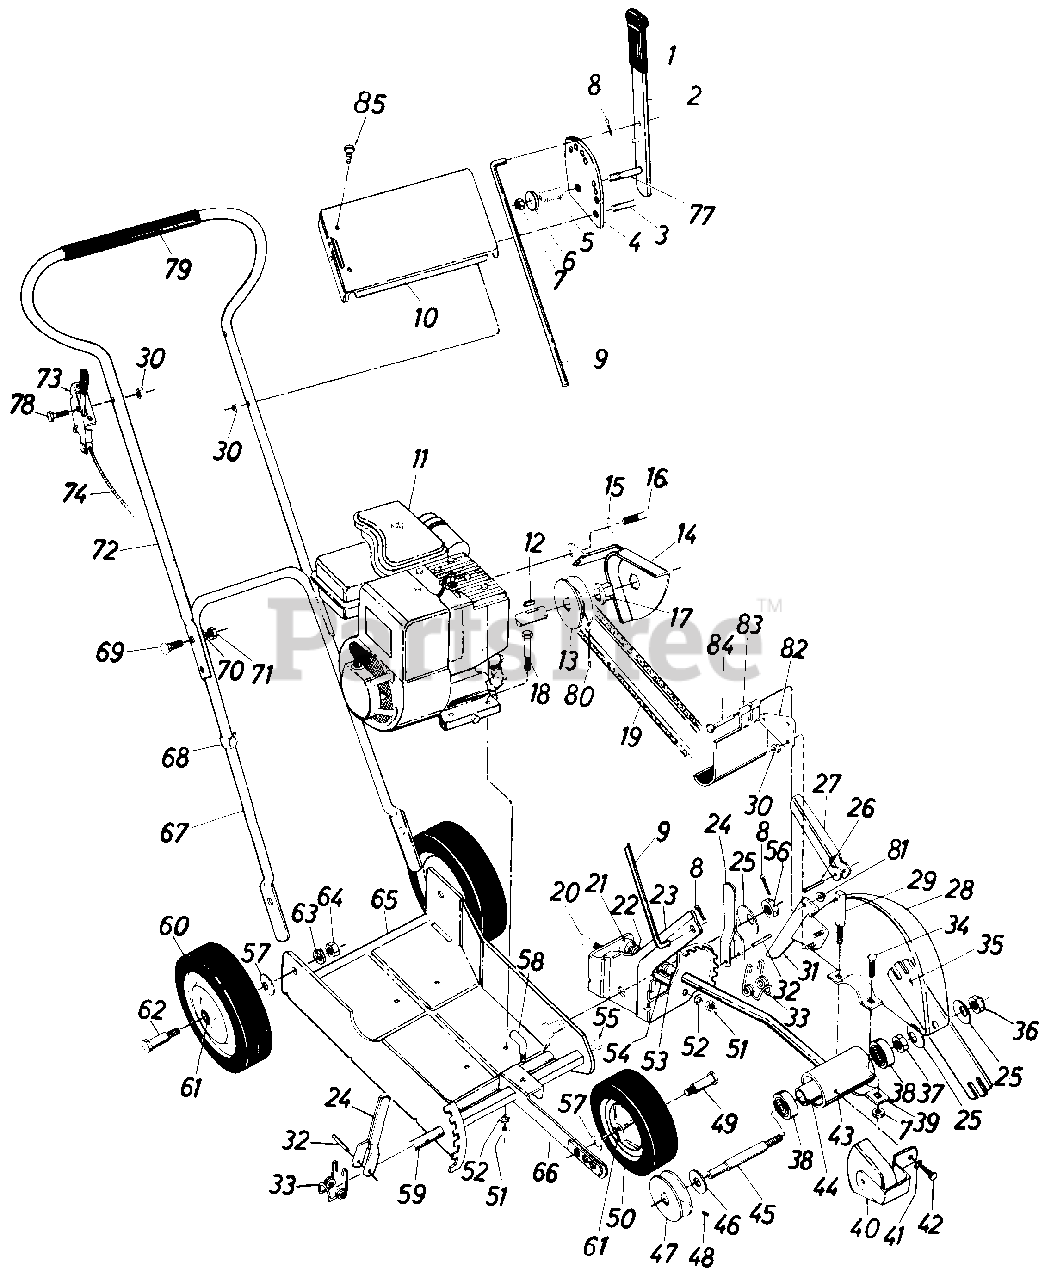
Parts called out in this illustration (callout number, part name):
1	Flat Bar Grip
2	Clutch Handle Assembly
3	Hex Bolt 1/4-20 x 1 1/4 Lg.
4	Clutch Plate
5	Compression Spring
6	Flat Washer
7	Hex Cent. L-Nut 5/16-18 Thd.
8	Cotter Pin 1/8 Dia. x 1.00" Lg.
9	Clutch Rod
10	Handle Cover
11	Engine
12	Square Key .187 Sq. x 1" Lg.
13	Pulley - Engine
14	Belt Guard Assembly
15	Internal L.-Wash. 1/2" Dia.
16	Hex Bolt 1/2-20 x 3/4" Lg.
17	Hex Bearing
18	Hex Bolt 5/16-18 x 1-1/2" Lg
19	V-Belt 3/8 x 31.2 Lg.
20	Hex Bolt 5/16-18 x 4 1/2" Lg
22	Compression Spring
23	Pivot Bracket Assembly
24	Lever Assembly
25	Belleville Washer
26	Roll Pin 5/32" x 3/4" Lg.
27	Cam Lever
28	Guard Assembly
30	Hex Cent. L-Nut 1/4-20 Thd.
32	Roll Pin 1/4" x 1 1/2" Lg.
33	Tension - Spring
34	Hex Bolt 5/16-18 x 1" Lg.
36	Hex Elastic Stop Nut 1/2-20 Thd.
37	Hex Jam Nut 1/2-20 Thd.
38	Bearing #203
39	Clamp Bracket
40	Belt Guard Assembly
41	L-Wash. 1/4 Scr.
42	Hex Wash.-Hd. Thd. Cut Scr. Type "F" 1/4-20 x 1/2 Lg.
43	Spindle Housing
46	Flat Washer .635 I.D. x .937 O.D. x .060
47	Pulley Spindle
48	Spiral Pin 3/16 Dia. x 1 1/4" Lg.
49	Axle Bolt Front Wheel
50	Wheel Assembly 7" Dia. - Front
51	Hex Nut 5/16-18 Thd.
52	L-Wash. 5/16" Scr.
53	Spiral Pin 3/16" Dia. 1" Lg.
55	Shoulder Bolt
56	Castle Hex Nut 1/2-20 Thd.
57	Belleville Washer
58	Lock Handle
60	Wheel Assembly 8" Dia. - Rear
61	Fortiflex Bearing
62	Axle Bolt - Rear
63	L. Wash. 3/8" Scr.
64	Hex Nut 3/8-16 Thd.
65	Base Assembly
66	Wheel Bracket Assembly
67	Handle - Lower
68	Cable Tie
69	Carriage Bolt 1/4-20 x 1 1/4 Lg.
70	L-Wash. 1/4" Scr.
71	Hex Nut 1/4-20 Thd.
72	Handle - Upper
73	Throttle Control Complete
74	Conduit and Wire
77	Hex Bolt 5/16-18 x 1.75" Lg.
78	Hex Bolt 1/4-20 x 1 1/2 Lg.
79	Grip - Handle
80	Set Screw 1/4-28 x .25" Lg
81	Push Cap 3/16"
82	Flap Bracket
83	Debris Deflector
84	Hinge Pin 3/16" x 1.75" Lg.
85	Truss Screw 10-24 x 2.25
